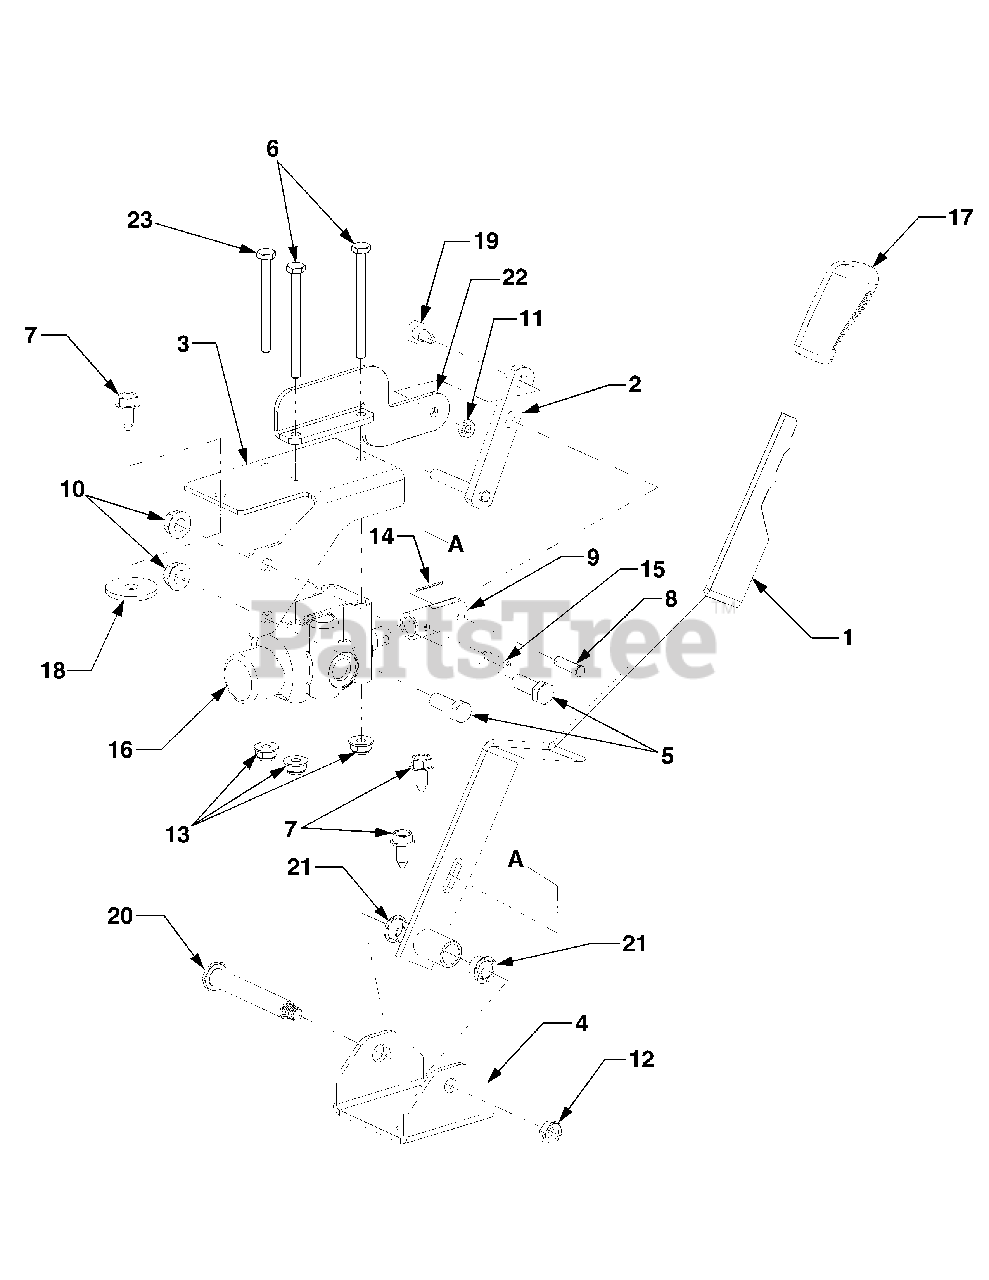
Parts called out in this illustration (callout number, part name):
1	Handle, Lift
2	Link, Valve
3	Bracket, Lift Valve Mounting
6	Screw, Hex Cap 1/4-20 x 3.0 GR5
7	Screw, Hex Wash, Hd Tapp 5/16-18 x.75
8	Pin, Clevis, .25 x .9375
9	Link, Valve
10	Nut, Hex Flange Nylon Lock, 3/8-16 GRF
11	Nut, Hex Jam, 1/4-20
12	Nut, Hex Ctr Lock Jam, 3/8-16 ..
13	Nut, Hex Flange Nylon Lock 14-20 GRF
14	Pin, Cotter, 1/16 x .75
15	Pin, Spirol, 3/16 x 1.0
16	Valve, Hydaulic Lift
17	Grip, Handle
18	Washer, Flat, .385 x 1.0 x .135
19	Screw, Shoulder, .34 x .285
20	Screw, Shoulder, .498 x 2.99
21	Bearing, Nylon Flange .5 ID
22	Link, Lift Valve Mounting
23	Screw, Hex Cap, 1/4-20 x 2.75 GR5
